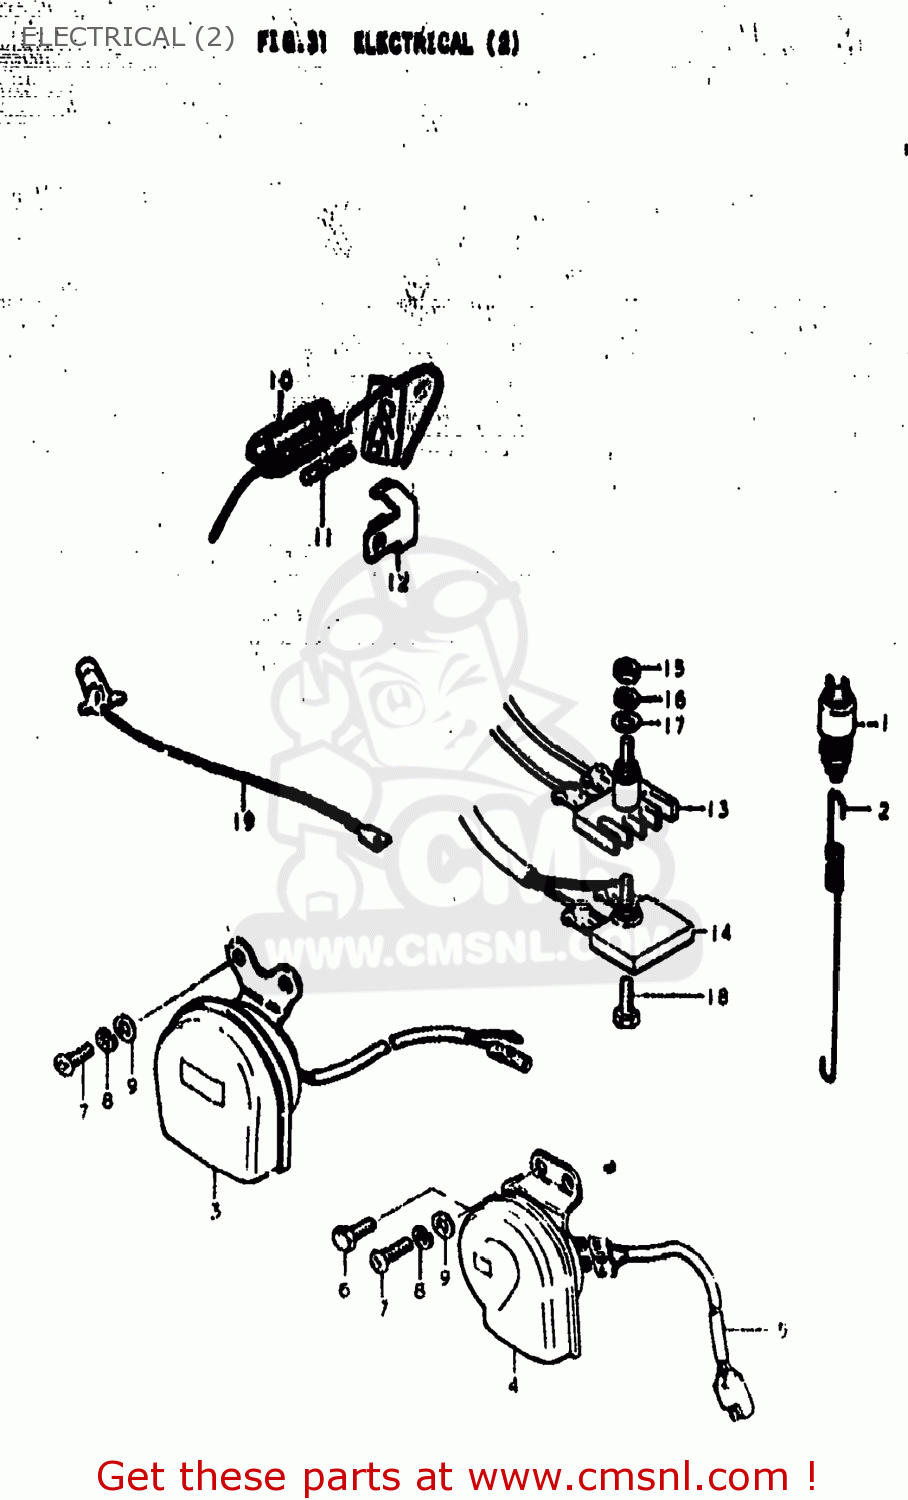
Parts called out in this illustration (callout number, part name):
1	SWITCH ASSY,BRAKE LAMP
2	SPRING
3	HORN ASSEMBLY
4	HORN ASSY
5	WIRE,HORN LEAD
6	BOLT
7	SCREW 6X12
8	LOCK WASHER
9	WASHER
10	BOX ASSEMBLY,FUSE
11	FUSE(15A)
12	HOLDER,FUSE CASE
13	RECTIFIER ASSEMBLY
14	RECTIFIER ASSEMBLY
15	NUT
16	LOCK WASHER
17	WASHER
18	BOLT
19	WIRE,WIRING HARNESS LEAD
